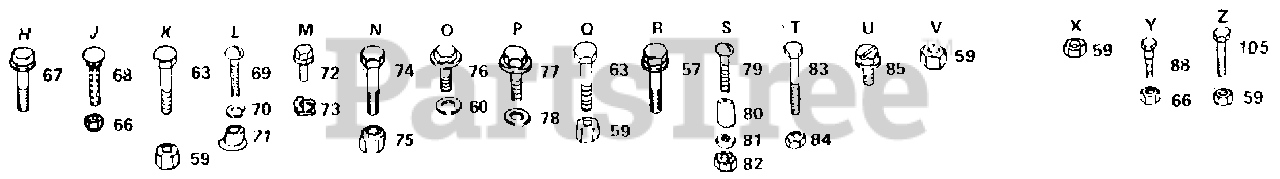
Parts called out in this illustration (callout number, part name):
57	SCREW
60	WASHER PM
63	BOLT
68	BOLT
69	SCREW
70	LOCKWASHER
71	WELDNUT
73	"""J"" FASTENER LT"
74	BOLT T
77	SCREW
78	WASHER
79	SCREW
80	SPACER LT
81	WASHER
83	BOLT
84	NUT GTV
85	SCREW LT
